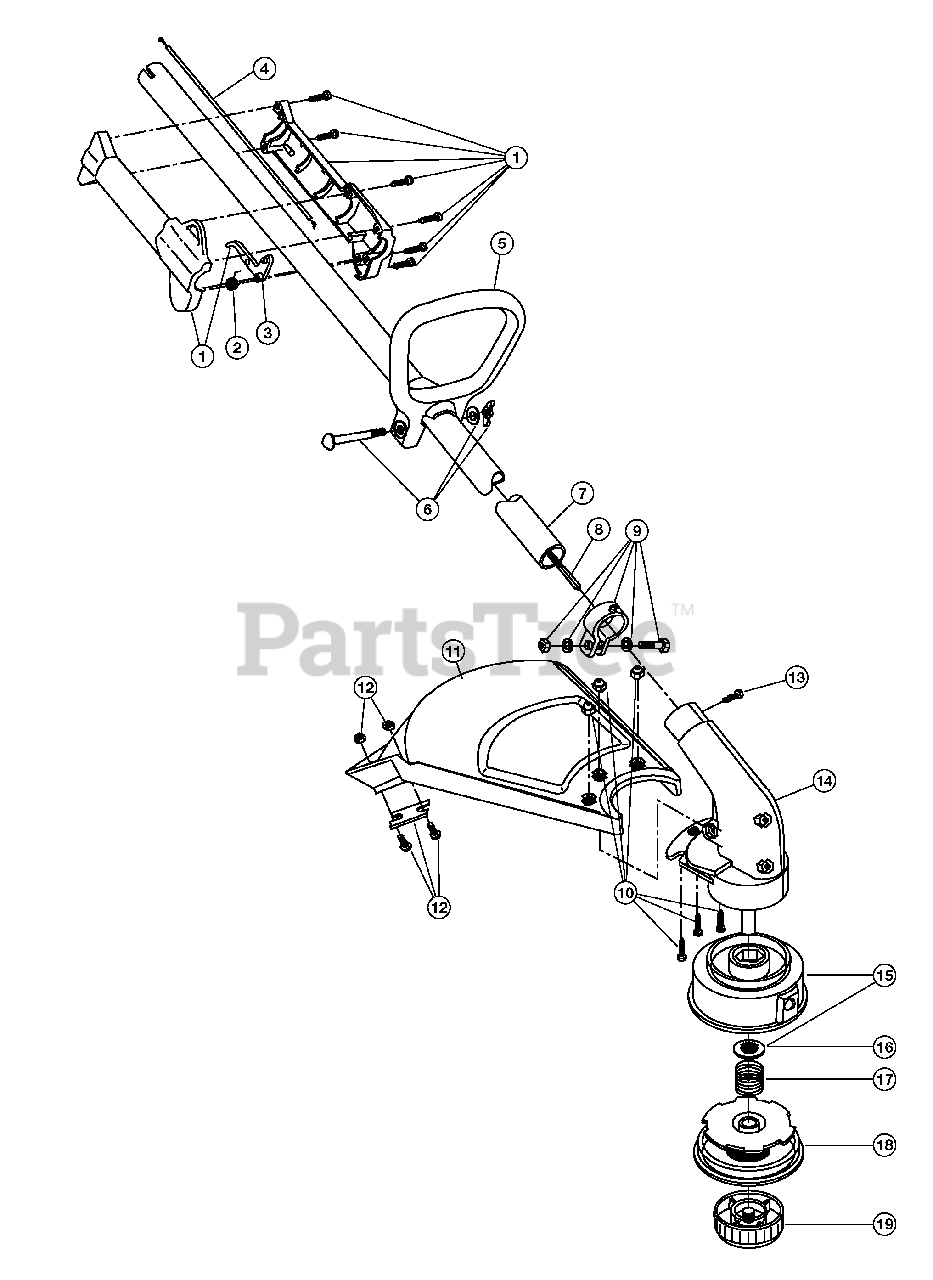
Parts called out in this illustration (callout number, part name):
1	Throttle Housing and Trigger Assembly
2	Throttle Trigger Spring
3	Throttle Trigger
4	Throttle Cable
5	D-Handle
6	D-Handle Hardware Assembly
7	Drive Shaft Housing Assembly
8	Flexible Drive Shaft
9	Lower Clamp Assembly
10	Guard Mounting Screw Assembly
11	Guard and Blade Assembly
12	Blade Assembly
13	Anti-Rotation Screw
14	Gearbox Assembly
15	Outer Spool and Eyelet Assembly
16	Retainer (10 pack)
17	Spring
18	Inner Reel
19	Bump Head Knob Assembly
